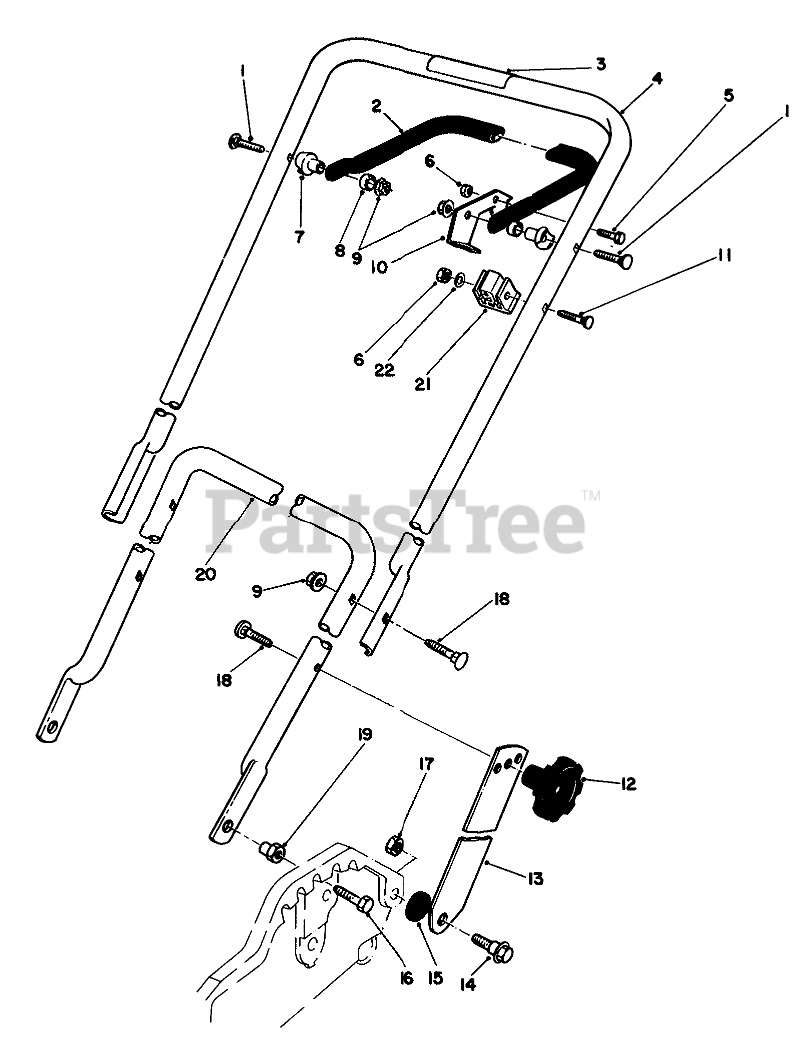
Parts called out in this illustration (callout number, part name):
1	5/16-18 X 2 HNDLE SCREW
2	Bar-Control
3	Decal-Danger
4	Handle-Upper
5	SCREW-HH
6	NUT-LOCK, NI
7	SPACER-SUPPORT
8	SPACER-NYLON
9	NUT-LOCK, NI
10	Lever-Control
11	HANDLE SCREW
13	Handle Latch
14	SCREW-SHOULDER
15	SPACER
16	SCREW-HH
17	NUT-LOCK, NI
18	SCREW
19	HANDLE PIVOT NUT
20	LOWER HANDLE
21	SUPPORT-CABLE
22	WASHER-FLAT
